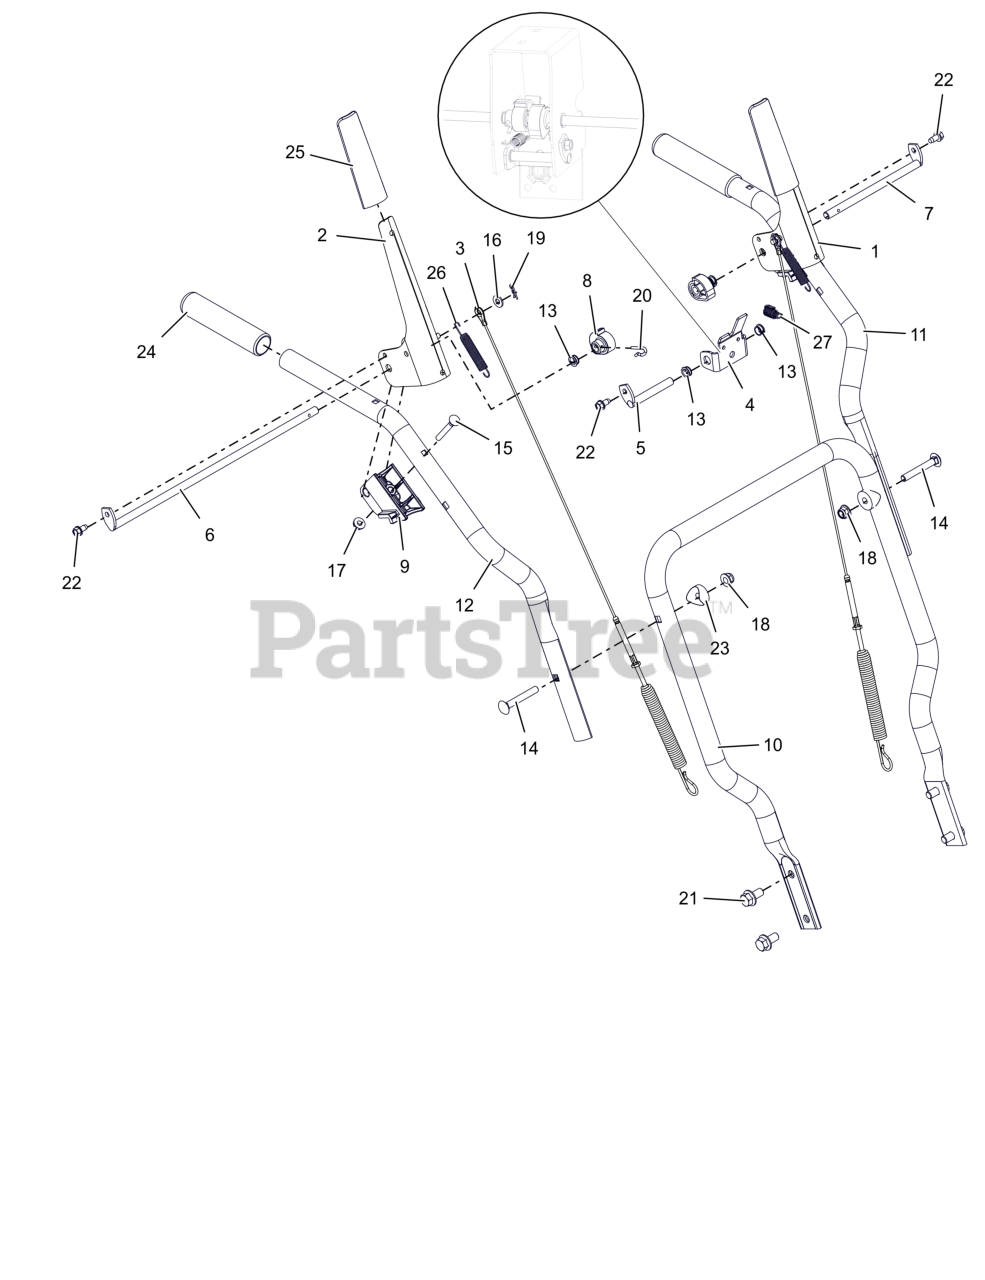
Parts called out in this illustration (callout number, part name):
1	LEVER, CLUTCH-LH
2	LEVER, CLUTCH-RH
3	CABLE, AUGER & UPPER TRACTION
4	BRACKET, INTERLOCK ARM
5	ROD, PIVOT - INTERLOCK
6	ROD, PADDLE MOUNT - LONG
7	ROD, PADDLE MOUNT - SHORT
8	CAM, INTERLOCK
9	BLOCK, CLUTCH PADDLE
10	HANDLEBAR, LOWER COMPACT (BLACK)
11	HANDLEBAR, UPPER - LH (BLACK)
12	HANDLEBAR, UPPER - RH (BLACK)
13	BUSHING, POLYLINER-.38 SNAPIN
14	BLT-RHSN.31-18X2.25 G5 TBZ 120
15	BLT-RDHDXLSQNK .25-20X2.0 G5YZ
16	WSHR,FLT .281X.625X.065 ZCC
17	NUT-LK-CTR-FLG .25-20 ZC120
18	NUT-NYL-FLG.31-18 GF TBZ 120WR
19	PIN, HAIR #178 .06X.77 ZCC
20	PIN, SPRING CLIP
22	SCR-TAP .25-20X.50 HWH ZCC
23	SPACER, HANDLEBAR
24	GRIP, HANDLEBAR
25	SLEEVE- CLUTCH PADDLE
26	SPRING, EXTENSION
27	SPRING-EXT .047X.438X1.45
